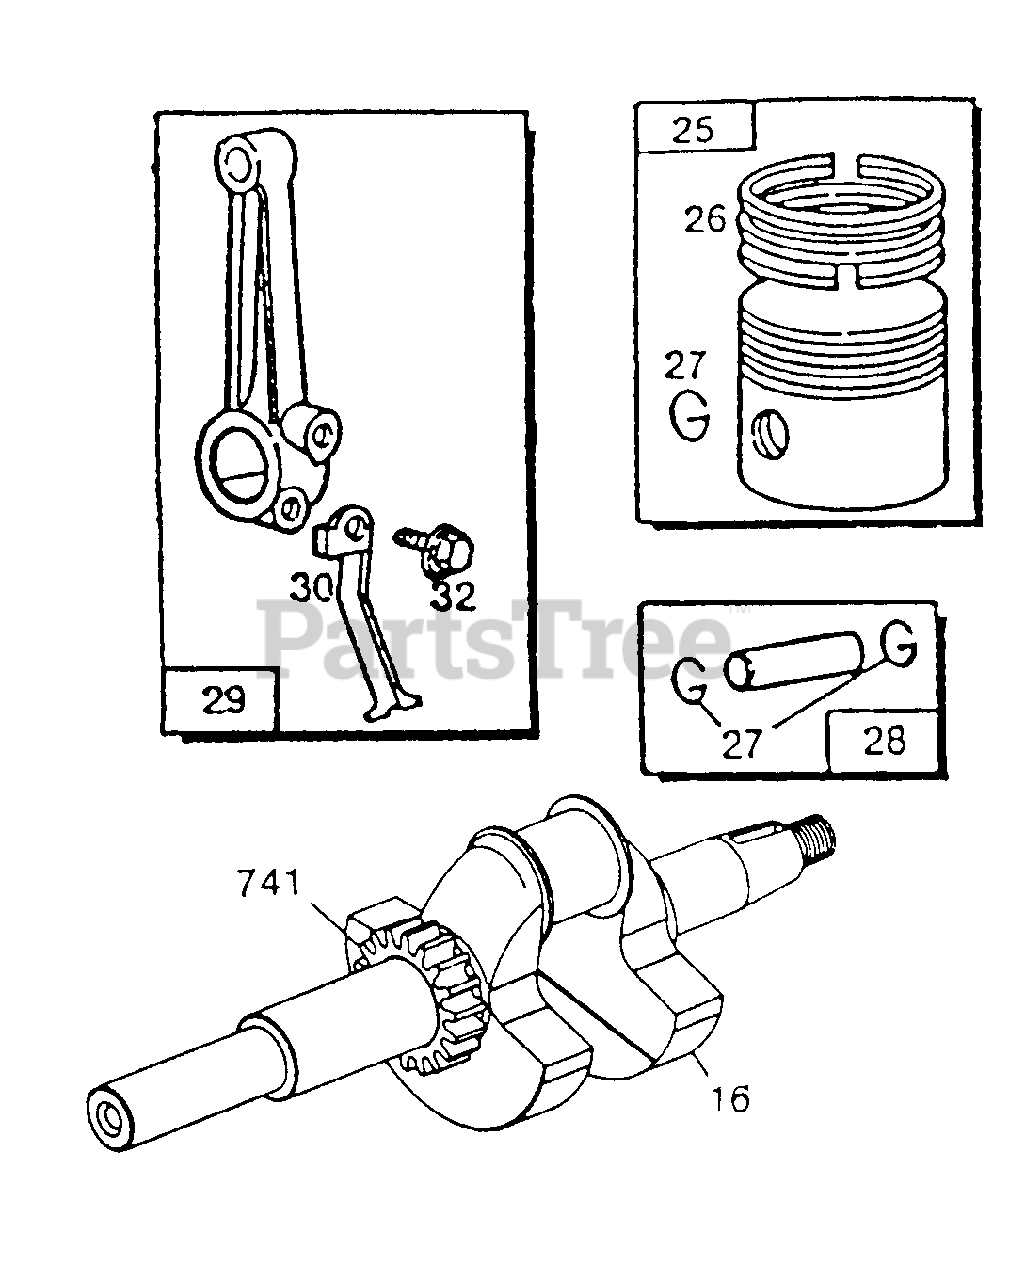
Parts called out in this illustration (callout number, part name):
16	Crankshaft
25	Piston Ass'y.-Std.
26	Ring Set-Std. Piston
27	Lock-Piston Pin
28	Pin Ass'y.-Piston (Std.)
29	Rod Ass'y.-Conn.
30	Dipper-Conn. Rod
32	Screw-Conn. Rod
741	Gear-Timing
